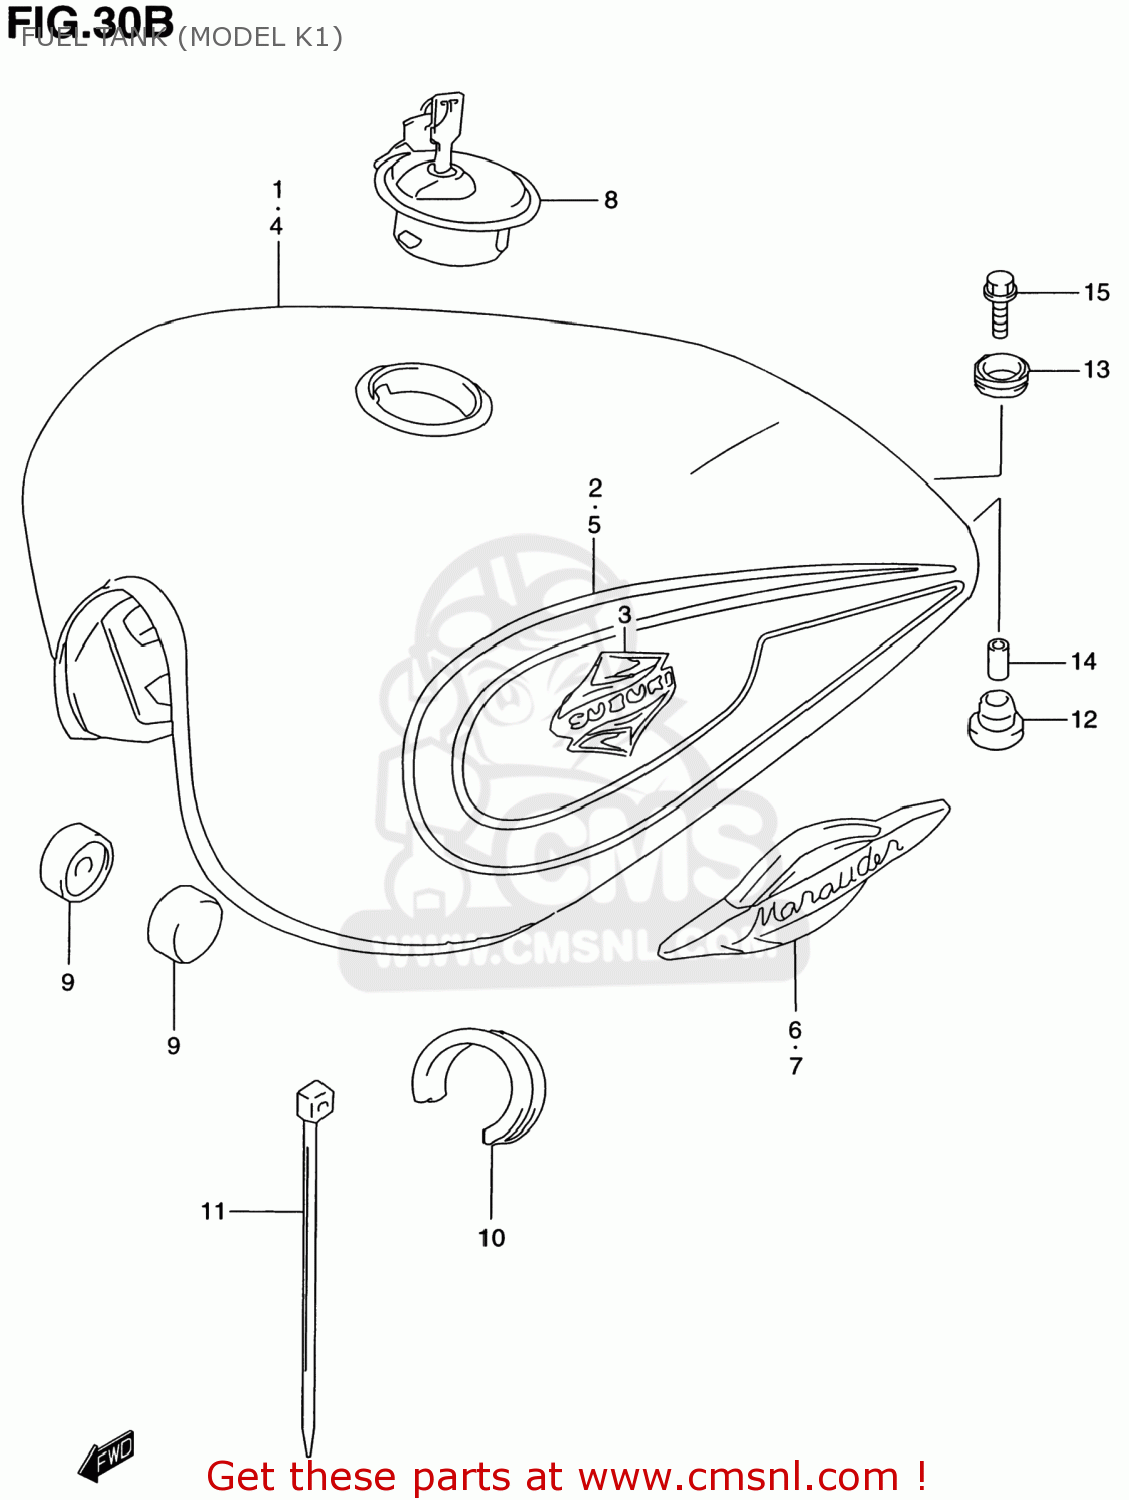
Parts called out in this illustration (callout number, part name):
1	TANK ASSY,FUEL
2	TAPE SET,FUEL TANK
3	EMBLEM,FUEL TANK
4	TANK ASSY,FUEL
5	TAPE SET,FUEL TANK
6	EMBLEM,FUEL TANK,RIGHT
7	EMBLEM,FUEL TANK,LEFT
8	CAP SET,FUEL TANK
9	CUSHION
10	CUSHION,FUEL TANK SIDE
11	CLAMP(L:250)
12	CUSHION
13	CUSHION,FUEL TANK RR
14	SPACER(6.5X9X18)
15	BOLT
